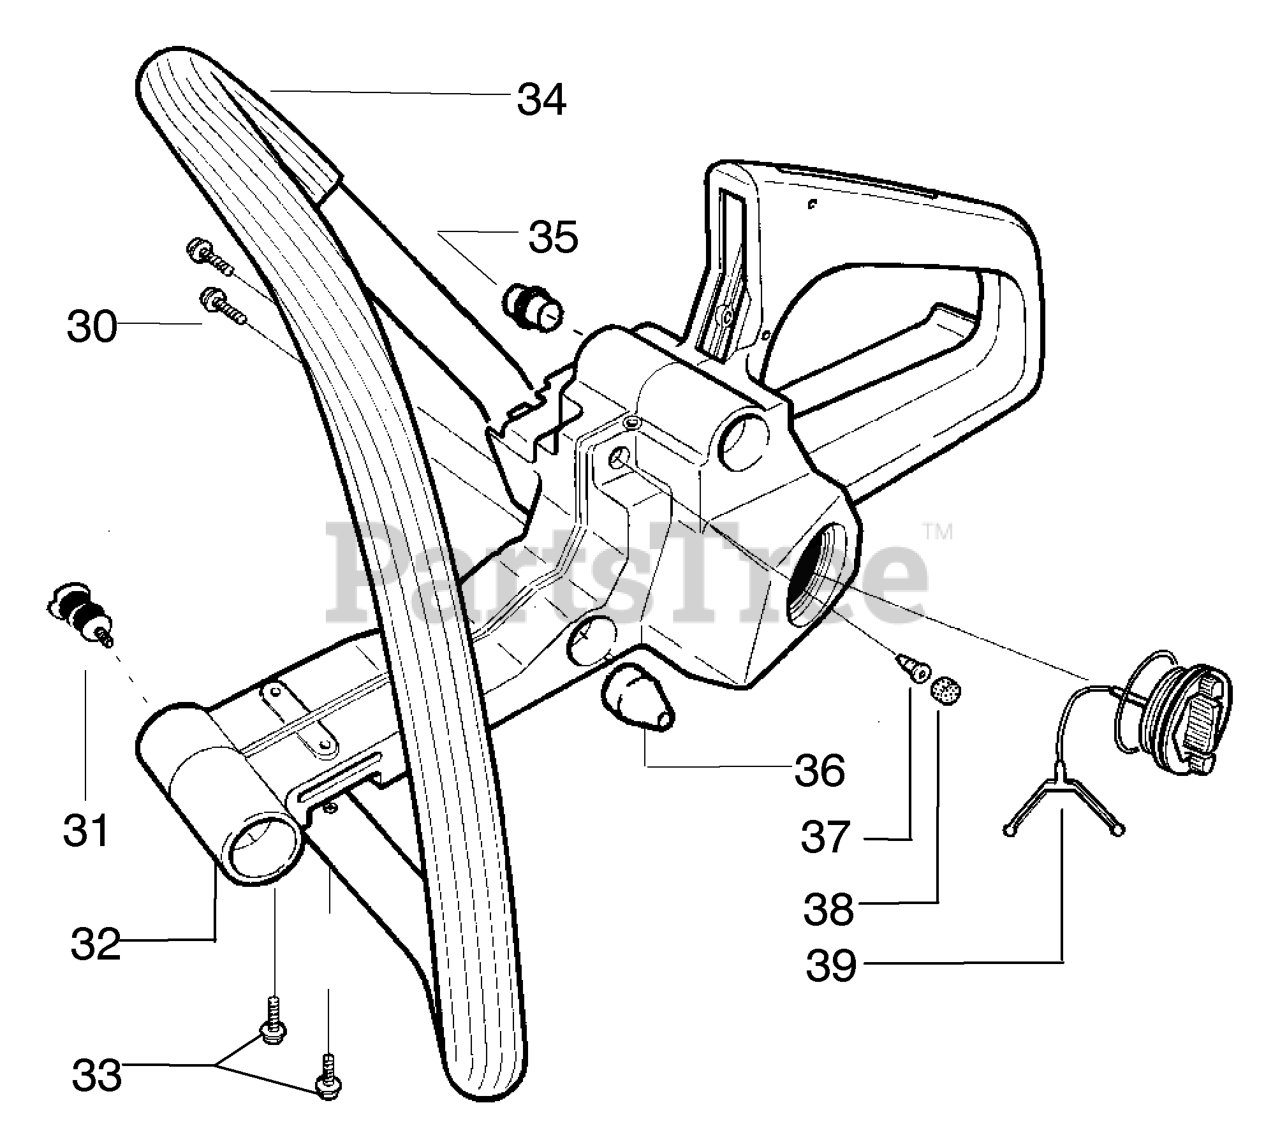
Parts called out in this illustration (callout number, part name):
32	TANK HANDLE ASSY
34	HANDLE FRONT
35	FRONT HANDLE ISOLATOR
36	SHOCK MOUNT(X2) 36/41
37	VALVE-CHECK (DUCKBILL)
38	BRONZE PLUG
39	FUEL CAP KIT
